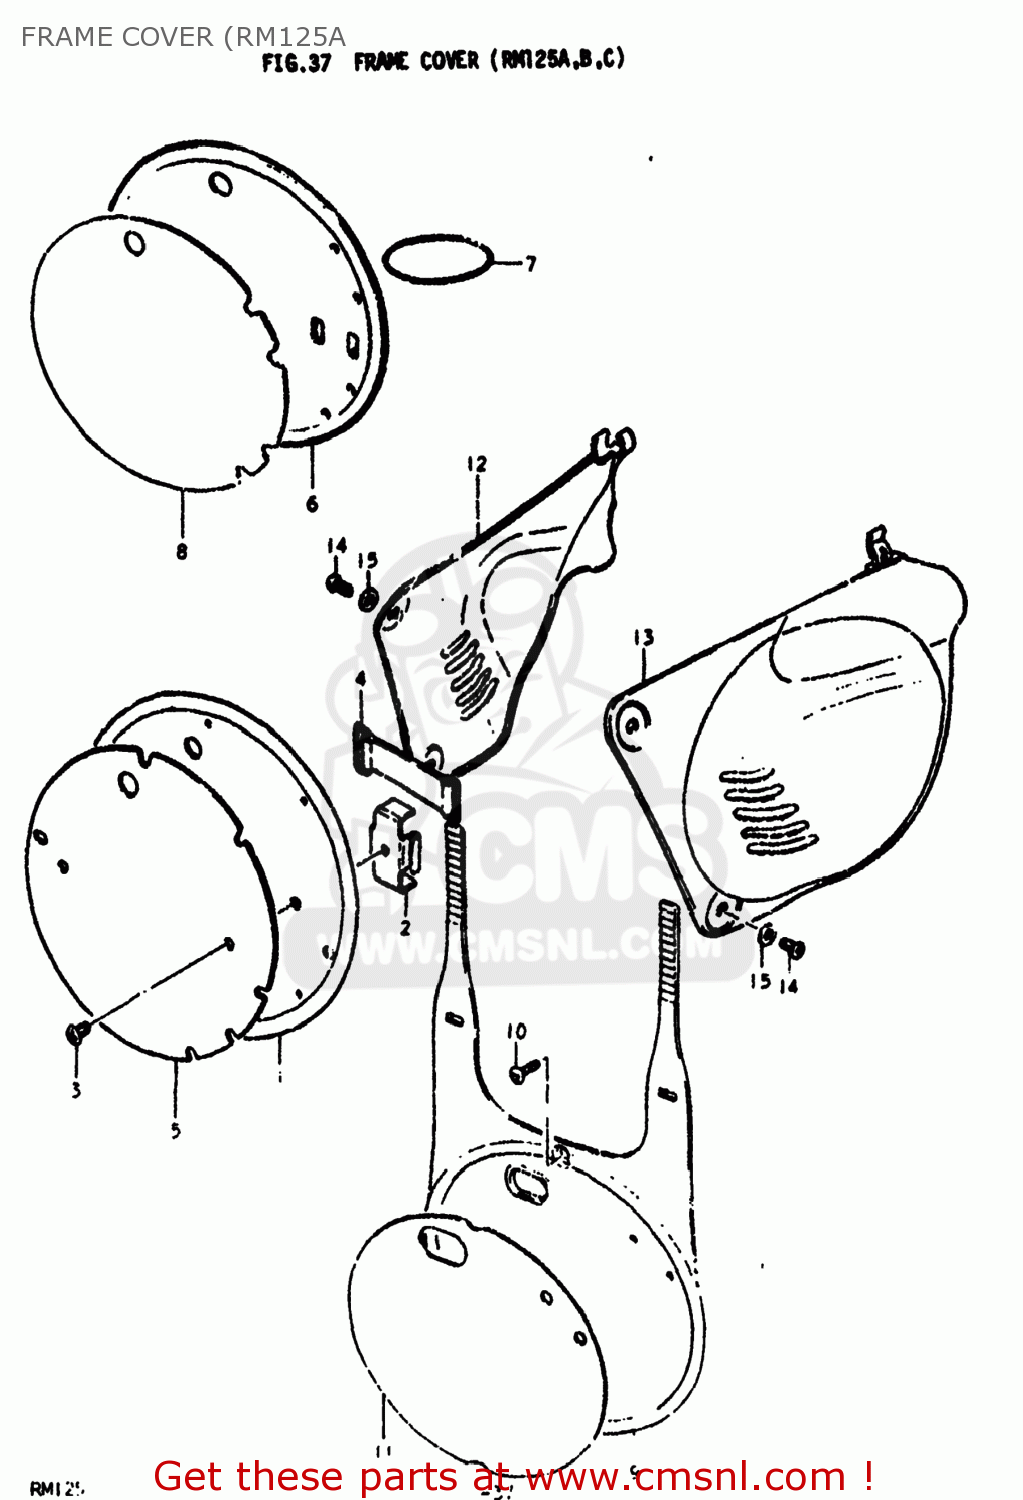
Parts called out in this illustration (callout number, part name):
1	PLATE SET,FRONT
3	SCREW 6X12
4	BAND
5	EMBLEM,FRONT NUMBER PLATE
6	PLATE,NUMBER,FRONT
7	O RING(D:3.53,ID:69.44)
8	EMBLEM,FRONT NUMBER PLATE
9	PLATE,FR NUMBER
10	(5X20) CROSS SCREW
11	EMBLEM,FRONT NUMBER PLATE
12	COVER,FRAME,R(BLACK)
13	COVER,FRAME,LEFT
14	SCREW 6X12
15	WASHER
